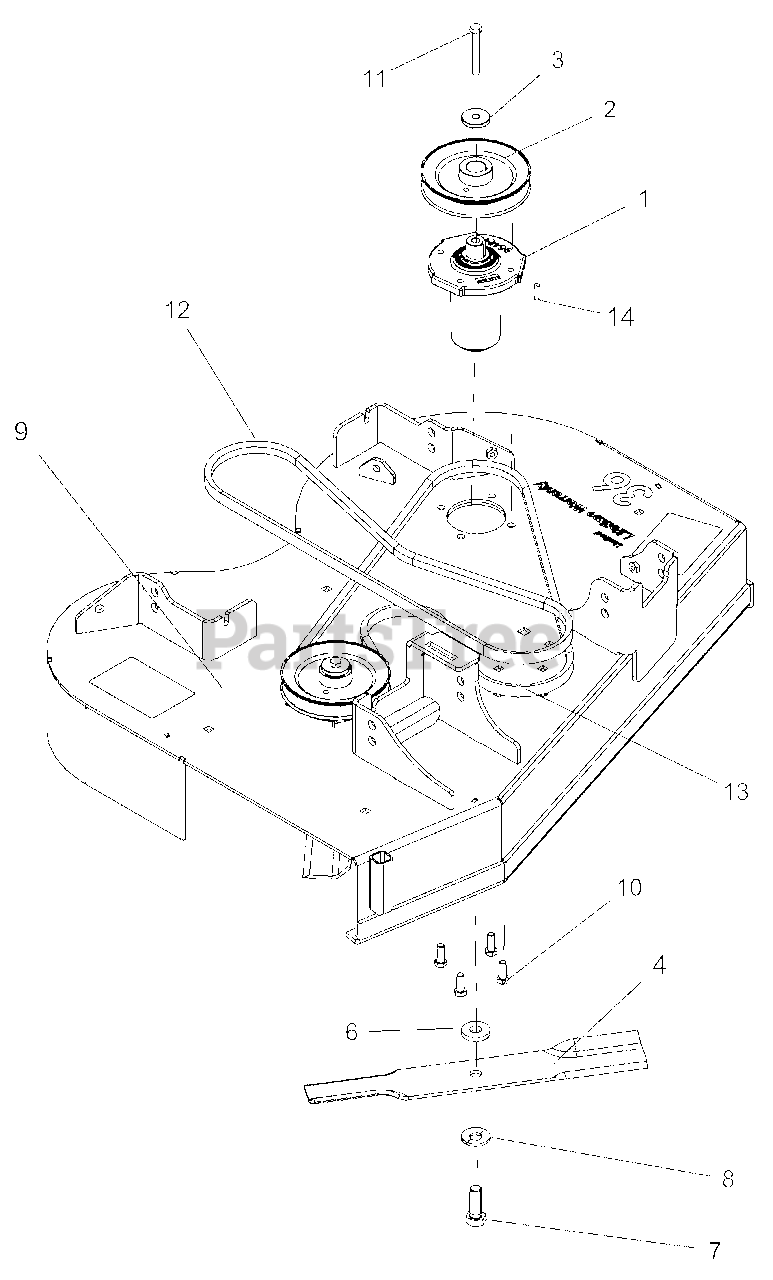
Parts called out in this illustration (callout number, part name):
1	SERVICE, ASM PINDLE- MAINT FREE (SHORT)
2	PULLEY, V-1" ID X 5.75" OD
3	RETAINER, SHEAVE SPINDLE
4	BLADE, 18.000 X .80 LIFT
6	WSHR-FL-STL .630X1.50X.25 YWZC
7	BLT, HEX .62-18X1.75 GR8 YWZC
8	WSHR, BLVL .63X1.625X.14
9	ASM, 36" DECK W/DECALS
10	BLT-HEX .38-16X1.00 GR5 YWZC EP30
11	BLT-HEX .38-16X2.75 GR8 YWZC
12	V-Belt, 5L-RAW EDGE
13	V-BELT, 5L SECTION
14	KEY-SQ .250X.250X.875 RC 40-50
